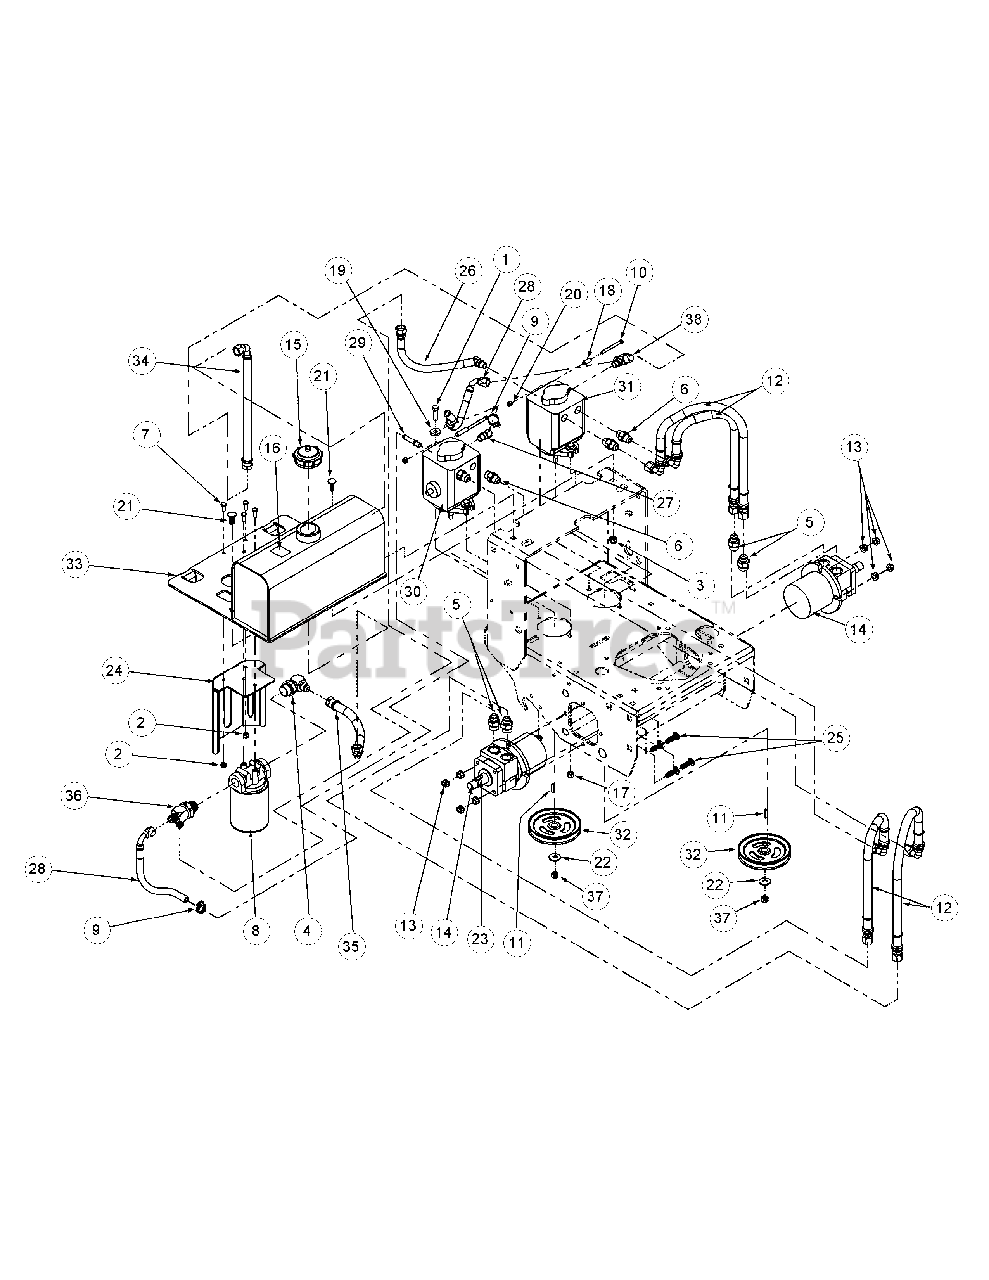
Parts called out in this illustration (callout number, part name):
1	Cap Screw, Standard, 3/8-16 x 1-1/4
2	Lock Nut Nylon Insert, 1/4-20
3	Lock Nut, 3/8-16
4	Elbow 90° 1/2 x 3/4
5	Fitting, Aeroquip
6	Fitting, Aeroquip
7	Cap Screw, 1/4-20 x 3/4
8	Filter Head 3/4 includes:
9	Worm Gear Clamp, 5/16-7/8
10	Cap Screw, Socket Head, 1/4-20 x 1-1/2 Zinc
11	Key, 3/16" x 7/8"
12	Reverse Pressure Hydraulic Hose Assembly
13	Flange Lock Hex Nut, 3/8-16
14	Hydraulic Motor, Wheel
15	Cap, Hydraulic Oil Tank
16	Oil Label, 20W-50
17	Lock Nut, 3/8-16
18	Spacer, Pump Release
19	Washer, Idler
20	Hex Lock Nut, 1/4-20
21	Carriage Bolt, 3/8-16 x 1.0
22	Bell Washer, .396 x 1.140 x .095
23	Woodruff Key, 3/16 x 3/4
24	Filter Guard Weldment
25	Carriage Bolt, 3/8-16 x 1.25
26	Left Pump Inlet Hose
27	Push On Fitting 45
28	Right Pump Inlet Hose
29	Push On Straight Fitting
30	Right Hand, Hydro Pump, BDP 10A 308
31	Left Hand, Hydro Pump, BDP 10A 413
32	Hydro Pump Pulley, 5.00 Dia
33	Fuel Tank Mounting Bracket and Integrated Hydraulic Tank
34	Left Hand, 14.25 Return Hose Assembly
35	9.5" Supply Hose Assembly
36	Tee Fitting, 3/4 x 1/2 x 1/2
37	Hex Nut, 3/8-24
38	Tee Fitting
